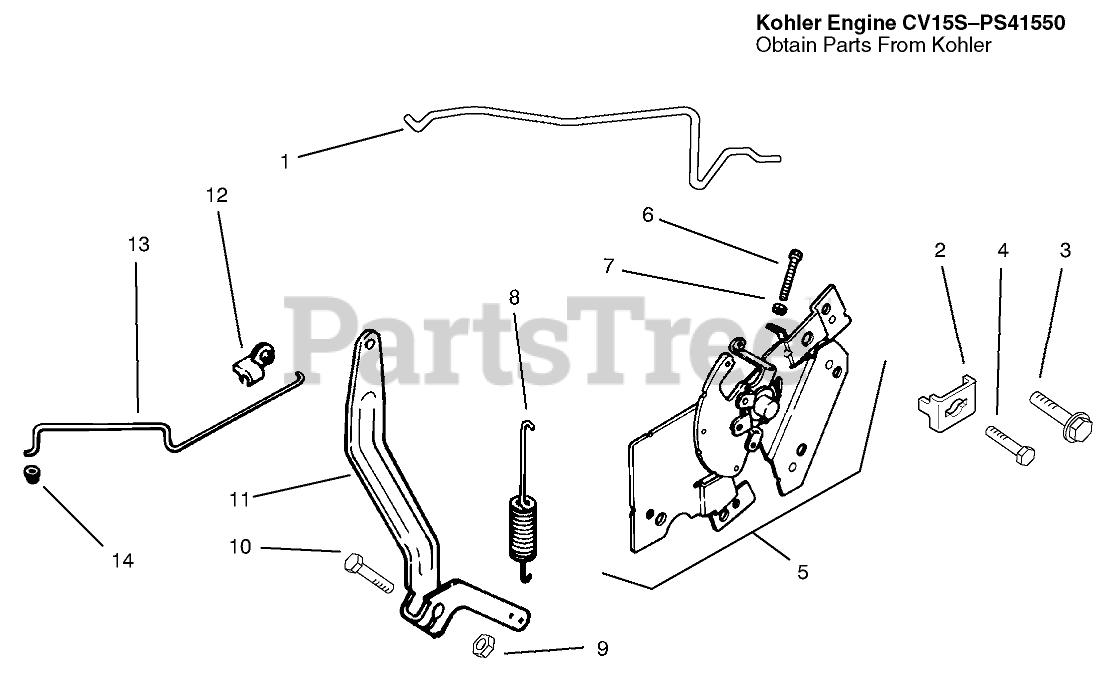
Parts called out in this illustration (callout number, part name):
1	Linkage Choke
2	Clamp
3	Screw Socket
4	Screw-HF
5	Control-Speed ASM
6	Screw
7	Nut
8	Spring-Governor
9	Nut
10	Screw
11	Lever-Governor
12	Bushing-Linkage
13	Linkage-Throttle
14	Bushing-Linkage
